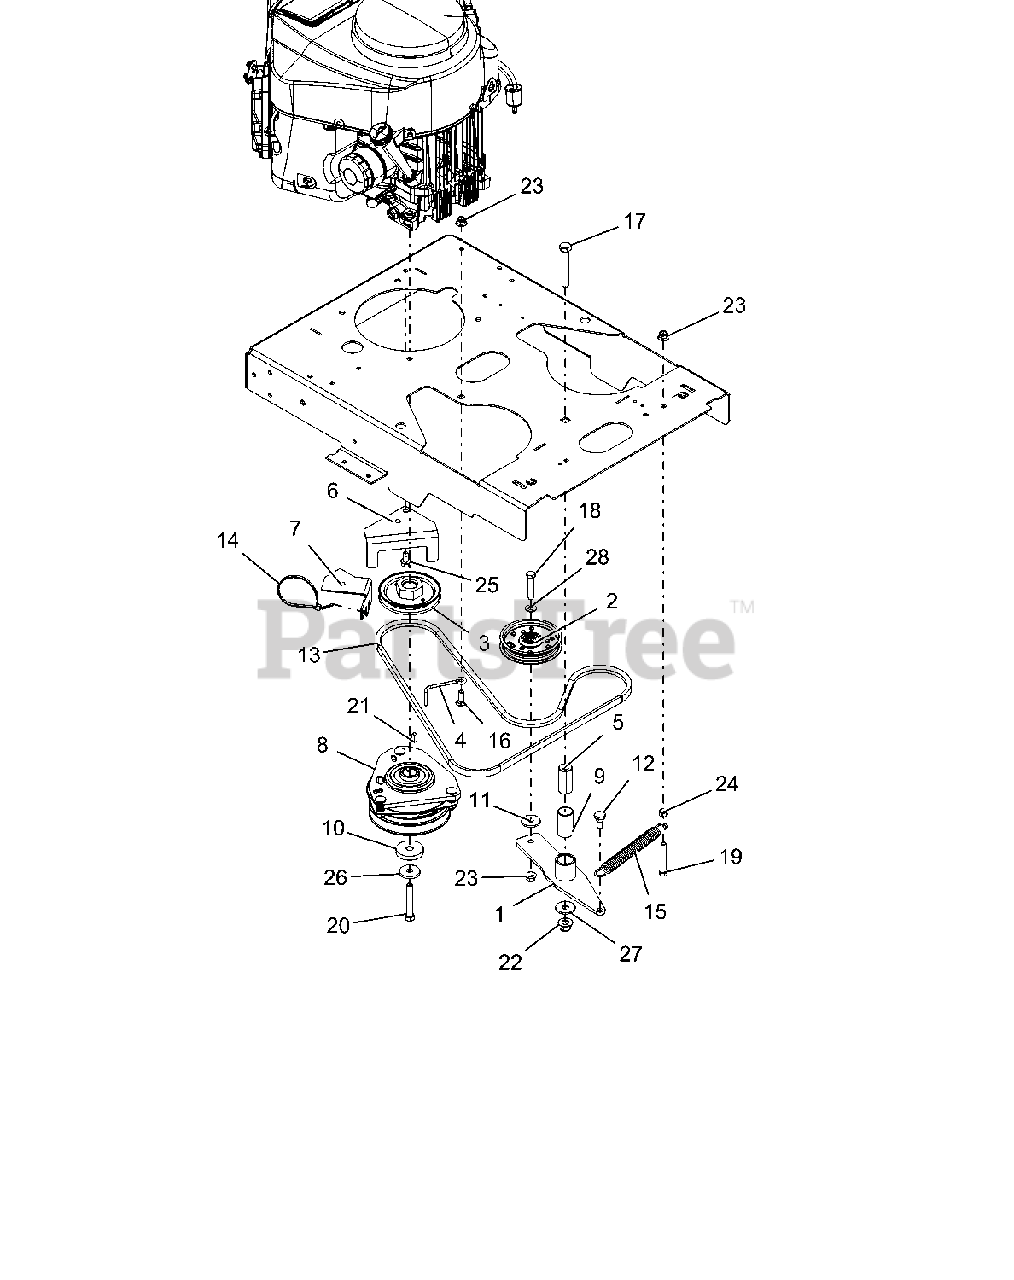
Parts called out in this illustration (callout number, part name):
1	HYDRO DRIVE IDLER ARM WMT
2	ASM, IDLER 4"
3	PULLEY, 4.50 OD X 1.002 ENGINE - LOW FILM
4	BELT, FINGER
5	BSHG, SPCR .502X.997X2.03
6	ANCHOR, OGURA CLUTCH - HD
7	HD CLUTCH WIRE GUARD - BLK
8	CLUTCH, OGURA GT1A
9	BSHG, 1.00X1.125X1.937
10	SPCR, .474/.459 X 2.00 X .350
11	WSHR-FL-STL .406X1.375X.135 YZ
12	BLT, SHLDR EP .38-16X.30 HEX YZ
13	V-BELT, 4L-WRAPPED CLUTCHING
14	CABLE, TIE 5.50 LG
15	SPRG, EXTENSION .120X.845X6.55 WLD
16	BLT-RDHDSQNK .38-16X1.00 G5 YWZC
17	BLT-HEX .50-13X3.25 GR5 YWZC
18	BLT-HEX .38-16X2.00 GR5 YWZC
19	BLT-HEX .38-16X2.50 GR5 YWZC
20	BLT-HEX .44-20X2.75 GR8 YWZC NYTORQ
21	KEY-SQ .250X.250X.625
22	NUT-LK-NYL-FLG .50-13 YWZC
23	NUT-LK-NYL-FLG .38-16 YWZC
24	NUT-HEX .38-16 YWZC
25	SCR-TAP .38-16X.75 HWH TR YWZ
26	WSHR, 7/16" SPRING DISC
27	WSHR-FL-STL .511X1.441x.125 YWZC
28	WSHR-FL-STL.406X.812X.065 YWZ
